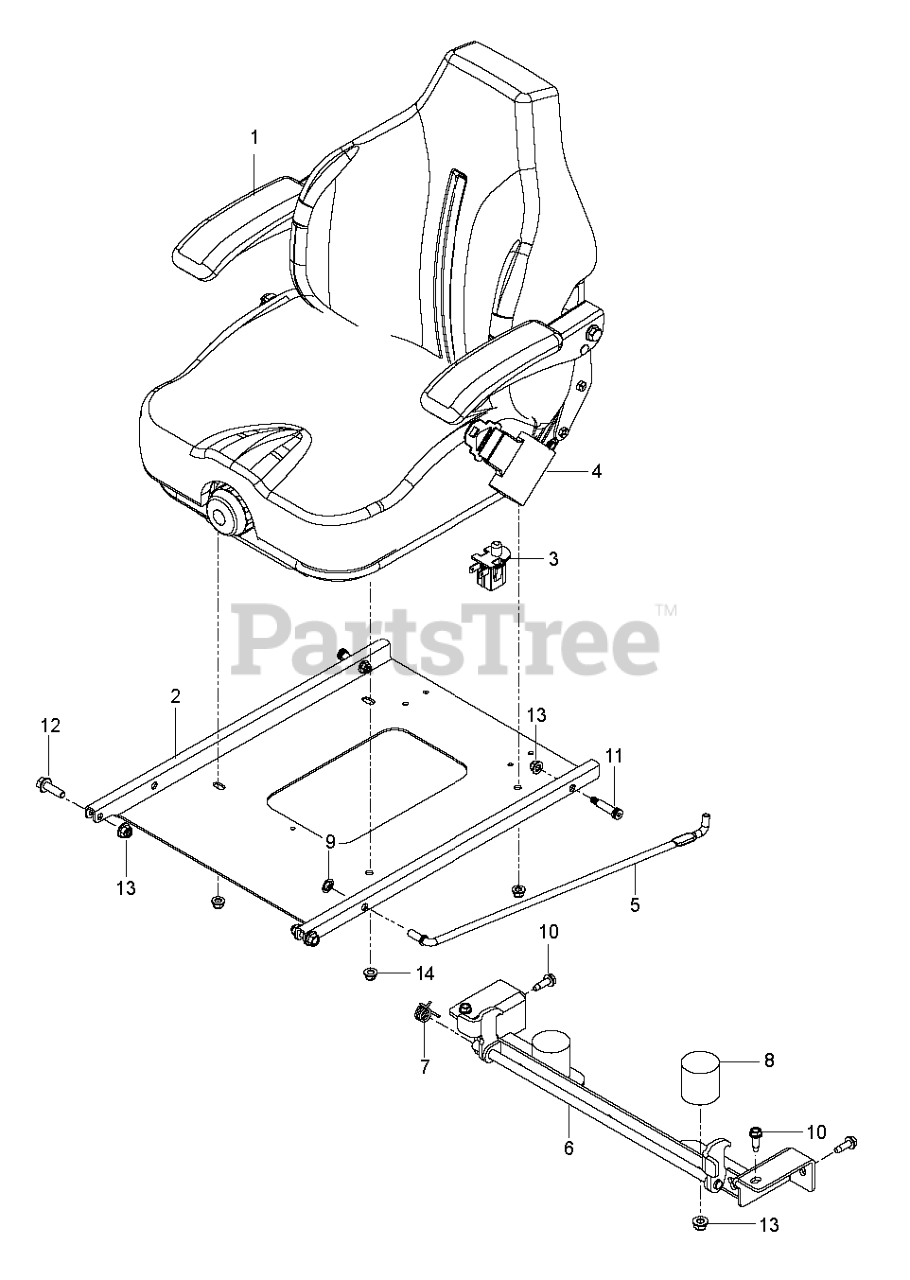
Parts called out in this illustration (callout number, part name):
1	SEAT.ASM.SUSPENSION.TRACK
2	PAN, SEAT, BLACK
4	SEAT BELT, RETRACTABLE
5	ROD, SEAT
6	BRACKET.PNT.LATCH.SEAT.BUMPER
7	SPRING, TORSION
8	BUMPER, RUBBER
9	NUT 3/8 PALNUT RTNG BLK PHOS
11	BOLT, SHOULDER 3/8 X 1.25
12	HHFS 3/8-16 X 1.25 GD 5
13	NUT 3/8-16 HEX FLG NYLOC ZD
14	5/16-18 NYLOC FLANGE NUT
